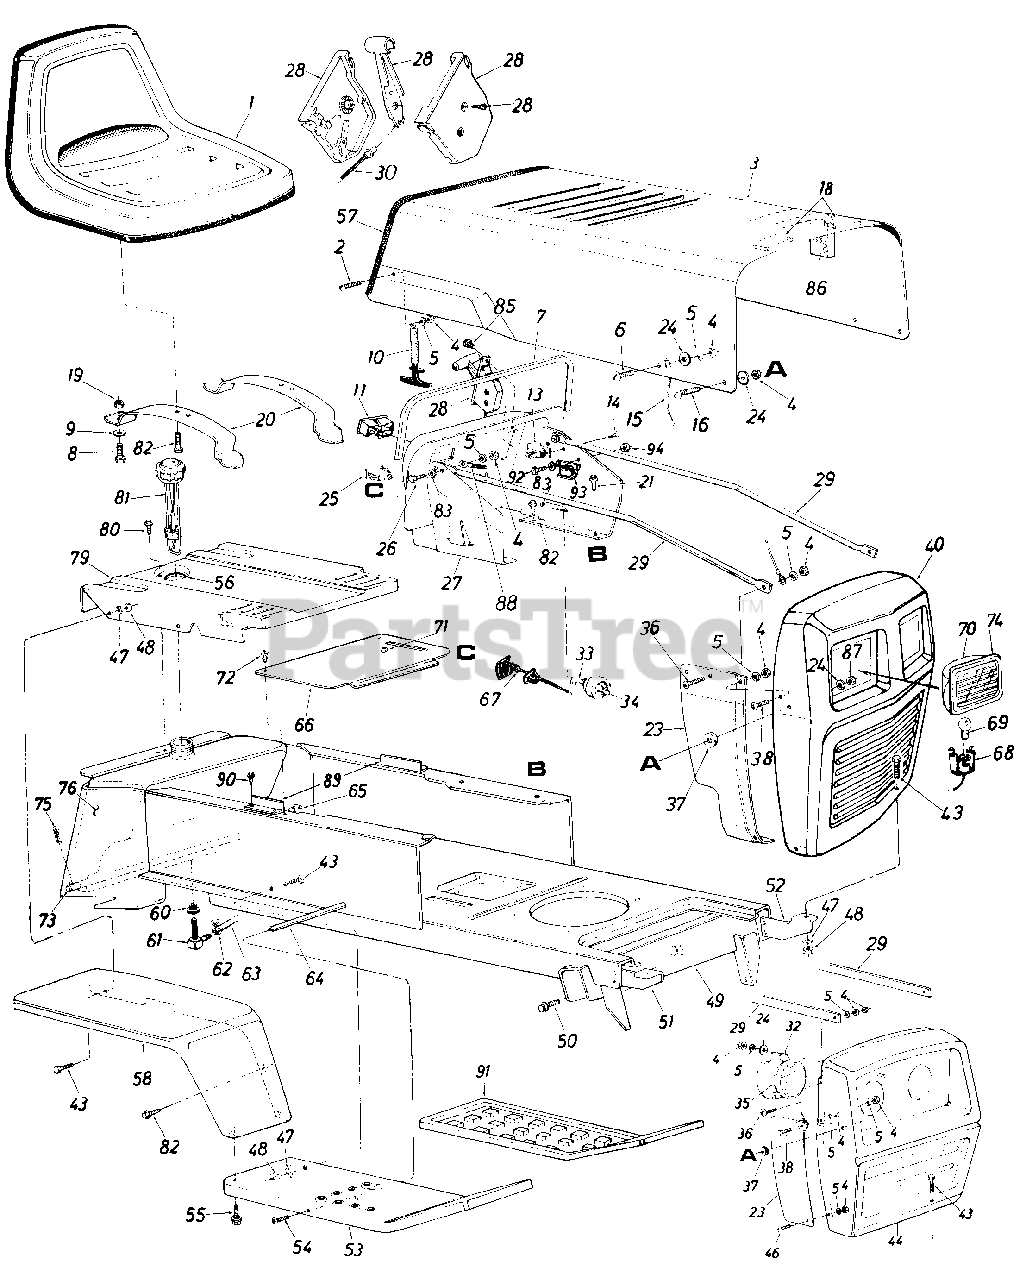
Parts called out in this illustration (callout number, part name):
1	Seat Assembly
2	Truss Mach. Scr. 1/4-20 x .50" Lg.
5	L-Wash. 1/4" I.D.
6	Truss Mach. Scr. 1/4-20 x .50" Lg.
7	Vinyl Molding Strip-29"
8	Hex Nylon Scr. 1/2-13 x .75" Lg.
9	Fl-Wash. .50" I.D. x 1.00" O.D. x.090
10	Hood Latch Ass'y.
11	Ammeter
13	Circuit Breaker 8 Amp.
14	Hex Tap Scr. #10 x .50"
15	Hood Stop
16	Truss Mach. Scr. 1/4-20 x .75" Lg.
18	PVC Foam Strip
19	Hex Nut 1/2-13 Thd.*
23	Grille Side Panel-R.H.
24	Fl-Wash. 1/4" I.D.
25	Light Switch
26	Truss Hd. Scr. 1/4-20 x 1.00" Lg.
27	Dash Panel Ass'y.
28	Throttle Control Box Comp.
29	Grille Positioning Rod
30	Throttle Control Cable
32	Head Lamp Retainer
33	Ignition Key
34	Ignition Switch
35	Head Lamp
36	Truss Machine Scr. 1/4-20 x .75" Lg.
37	Rubber Washer
38	Truss Mach. Scr. 1/4-20 x .50" Lg.
44	Grille (Painted)
46	Truss Mach. Scr. 1/4-20 x .50" Lg.
47	L-Wash. 5/16" I.D.
48	Hex Nut 5/16-18 Thd.
49	Lower Frame Ass'y.
50	Hex Thd. Rolling Scr. 5/16" x.75" Lg.
51	Grille Mount Brkt.-R.H.
52	Grille Mount Brkt.-L.H.
53	Running Board-R.H.
54	Truss Mach. Scr. 5/16-18 x .75" Lg.
55	Hex Thd. Rolling Scr. 5/16-24 x .75" Lg.
56	Grommet
57	Vinyl Moulding Strip-31"
58	Fender Ass'y.-R.H.
60	Bushing
61	90ø Nipple
62	Hose Clamp 3/8"
63	Gas Line 46" Lg.
64	Running Board Rod
65	Speed Nut #10-24
66	Transmission Cover Ass'y.
67	Choke Control Comp.
68	Socket
69	Lamp
70	Headlight Housing
71	Snap Bushing
72	Truss Hd. Scr. #10 x .50"
73	Hitch Rod
74	Lens
75	Internal Cotter Pin
76	Gas Tank
79	Seat Plate
80	Hex Thd. Rolling Scr. 5/16-24 x .75" Lg.
81	Gas Gauge
82	Hex Thd. Rolling Scr. 5/16-24 x .75" Lg.
83	External Wash. 1/4" I.D.
85	Truss Mach. AB-Tap Scr. #10 x .50" Lg.
86	PVC Foam Strip
87	Hex L-Nut 1/4-20 Thd.
88	Ground Wiret
89	Seat Spring Guide
90	Hex AB-Tap Scr. 1/4 x .625" Lg.
91	Foot Pad
92	Hex Bolt 1/4-20 x .5" Lg.
93	Solenoid
94	Hex Sems Nut 1/4-20 Thd.
